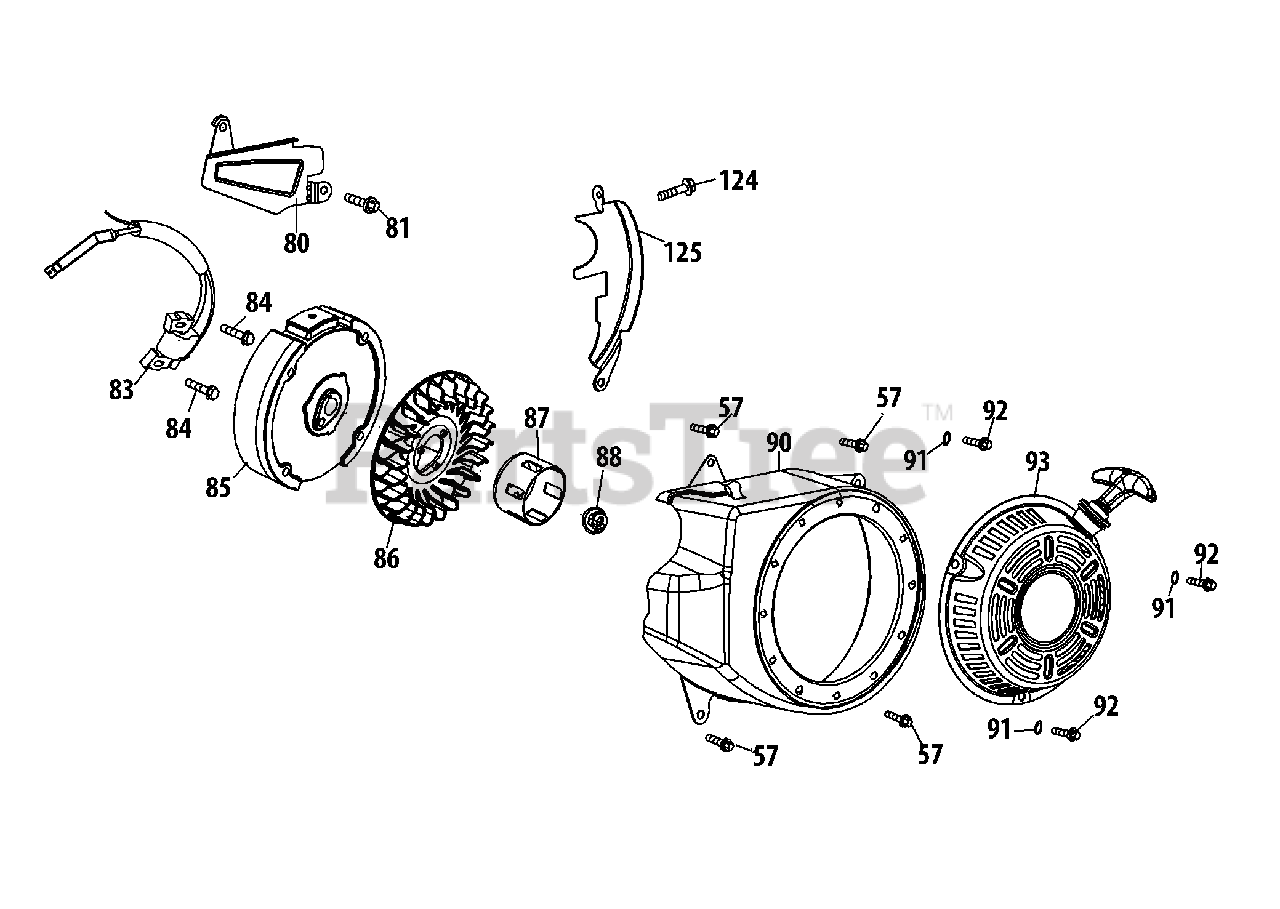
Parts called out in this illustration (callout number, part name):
57	Bolt M6×12
80	Air Flow Shield
81	Bolt M6×10
83	Ignition Coil
84	Flange Bolt M6X25
86	Cooling Fan
87	Starter Cup
88	Flywheel Nut, M14 X 1.5
90	Blower Housing
91	Flat Washer
92	Bolt M6×10
93	Recoil Starter Assembly
124	Bolt:Flange M6X20
125	Blower Housing Shield
